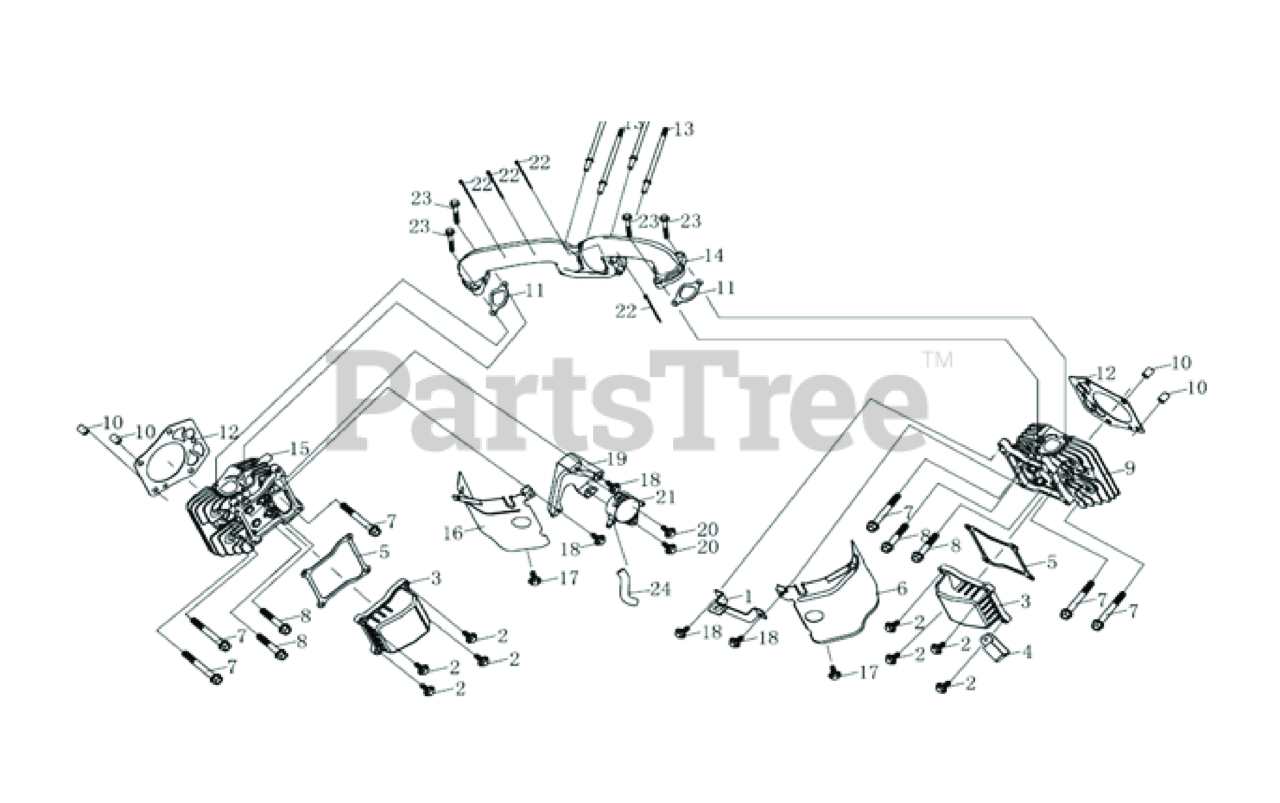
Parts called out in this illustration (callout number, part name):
1	Bushing, .376" I.D. Oilite
2	Bolt, Flange
3	BUSHING
4	Cleat, Cable
5	BUSHING, OILITE, .627 ID
6	Deflector, Air
7	Bolt, Flange
8	Bolt, Flange
9	BRONZE BUSHING, 7/8 ID X 1.0 FLANGED
10	Pin, Location
11	Gasket
12	BUSHING
14	Manifold, Intake
15	Bushing, Oilite - 1.00 ID
16	Deflector, Air
17	Bolt, Flange
18	Bolt, Flange
19	Bracket, Fuel Pump
20	Bolt, Flange
21	Fuel Pump
22	Cable Tie
23	Bolt Flange
24	Tube, Breather
